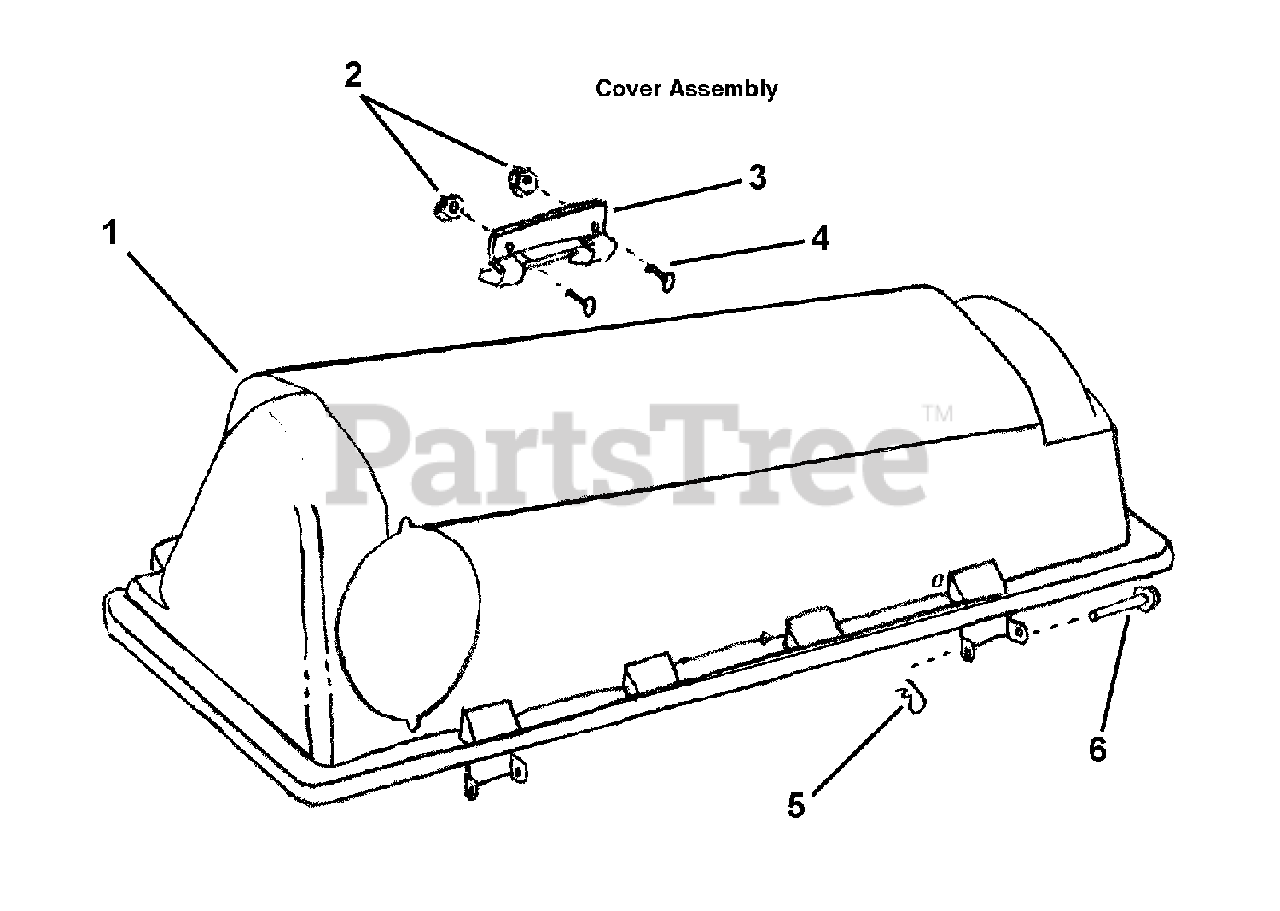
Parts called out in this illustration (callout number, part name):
1	COVER ASSY, TRIPLE
2	NUT, HEX LOCK 10C W/ NYL INSERT
3	HANDLE, COVER
4	SCREW, TRUSS HEAD PHILLIPS, #10-24 X 3/4
5	CLIP, HAIR PIN
6	PIN, COVER HINGE
